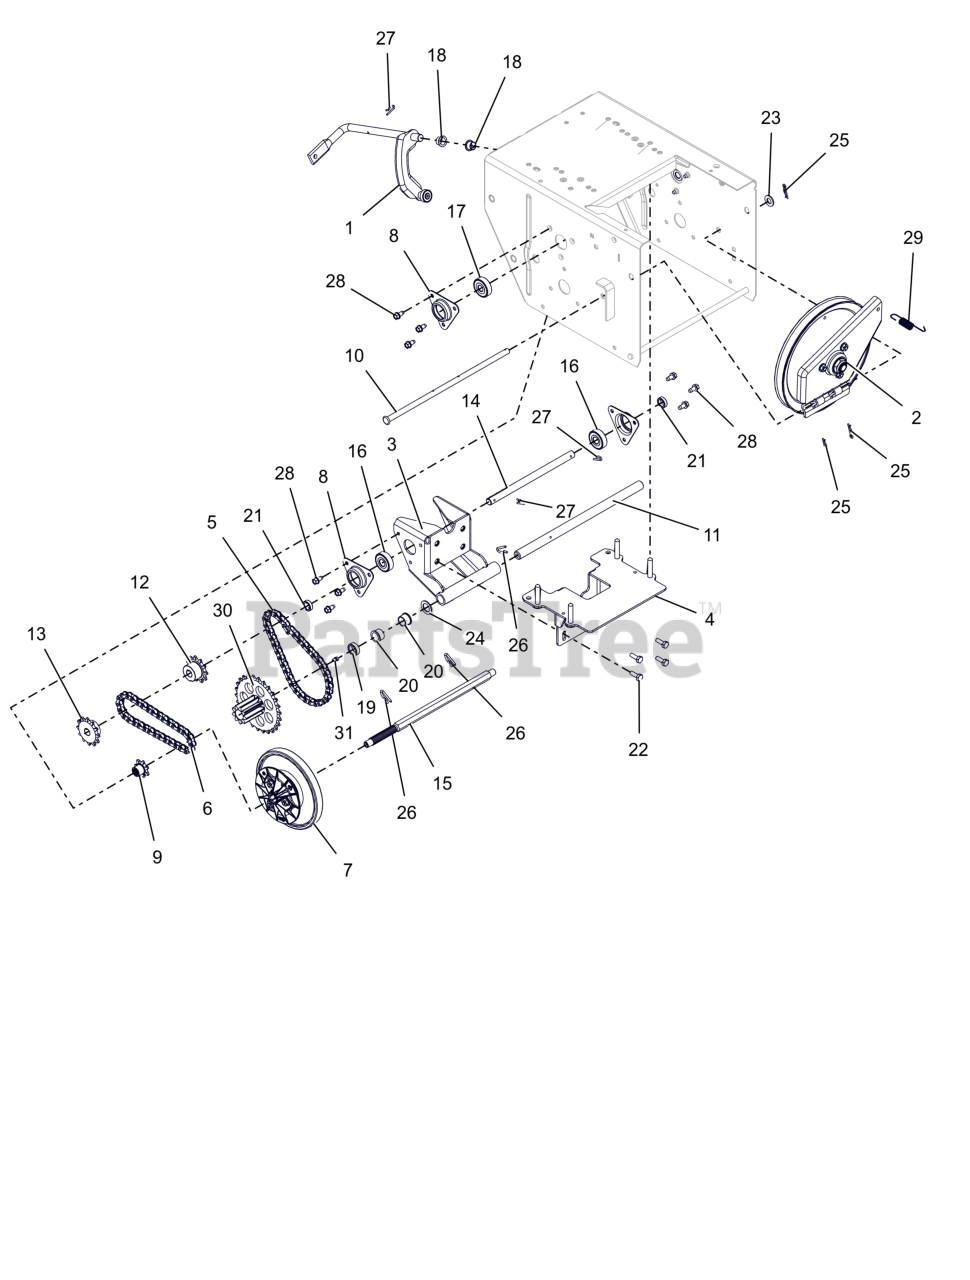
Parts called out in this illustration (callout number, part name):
1	ARM, SHIFT - ASSEMBLY
2	PLATE, SWING ASSEMBLY-DEEP
3	WLDMT, TRIPLE REDUCTION BRKT
4	STRAP, TRIPLE REDUCTION MEDIUM
5	CHAIN, ROLLER - #41X36 PITCHES
6	CHAIN - #41, 32 PITCHES
7	DISC, FRICTION DRIVE-ASSEMBLY
8	FLANGE, BEARING
9	SPROCKET, PINION 7T W/SPLINE
10	PIN, PIVOT
11	SHAFT, PINION-HARDENED
12	SPROCKET, 11 TOOTH
13	SPROCKET, 12 TOOTH
14	SHAFT, REDUCTION HEAT TREATED
15	SHAFT, HEX HEAT TREATED SPLINE
16	BRG-BALL .500X1.38X.437
17	BRG-BALL .437X1.375X.437
18	BUSHING, POLYLINER-.50 SPLIT
19	BSHG-SLV, .635X.880X.305
20	BSHG-FLG .625X.750X.500X.875
21	SPCR, SLV
22	BLT, HEX .25-20X.75 G5 ZCC
23	WSHR,FLT .406X.812X.065 ZCC
24	WSHR, FLT .630X1.005X.062 ZCC
25	PIN, HAIR #225 .072X1.09
26	PIN, SPRING CLIP
27	CLIP, SPRING
28	SCR-TAP .25-20X.50 HWH ZCC
29	SG-TENS .048X.50X2.8
30	PINION & SPROCKET
31	ZERK,FITTING .25X.125 DRIVE IN
